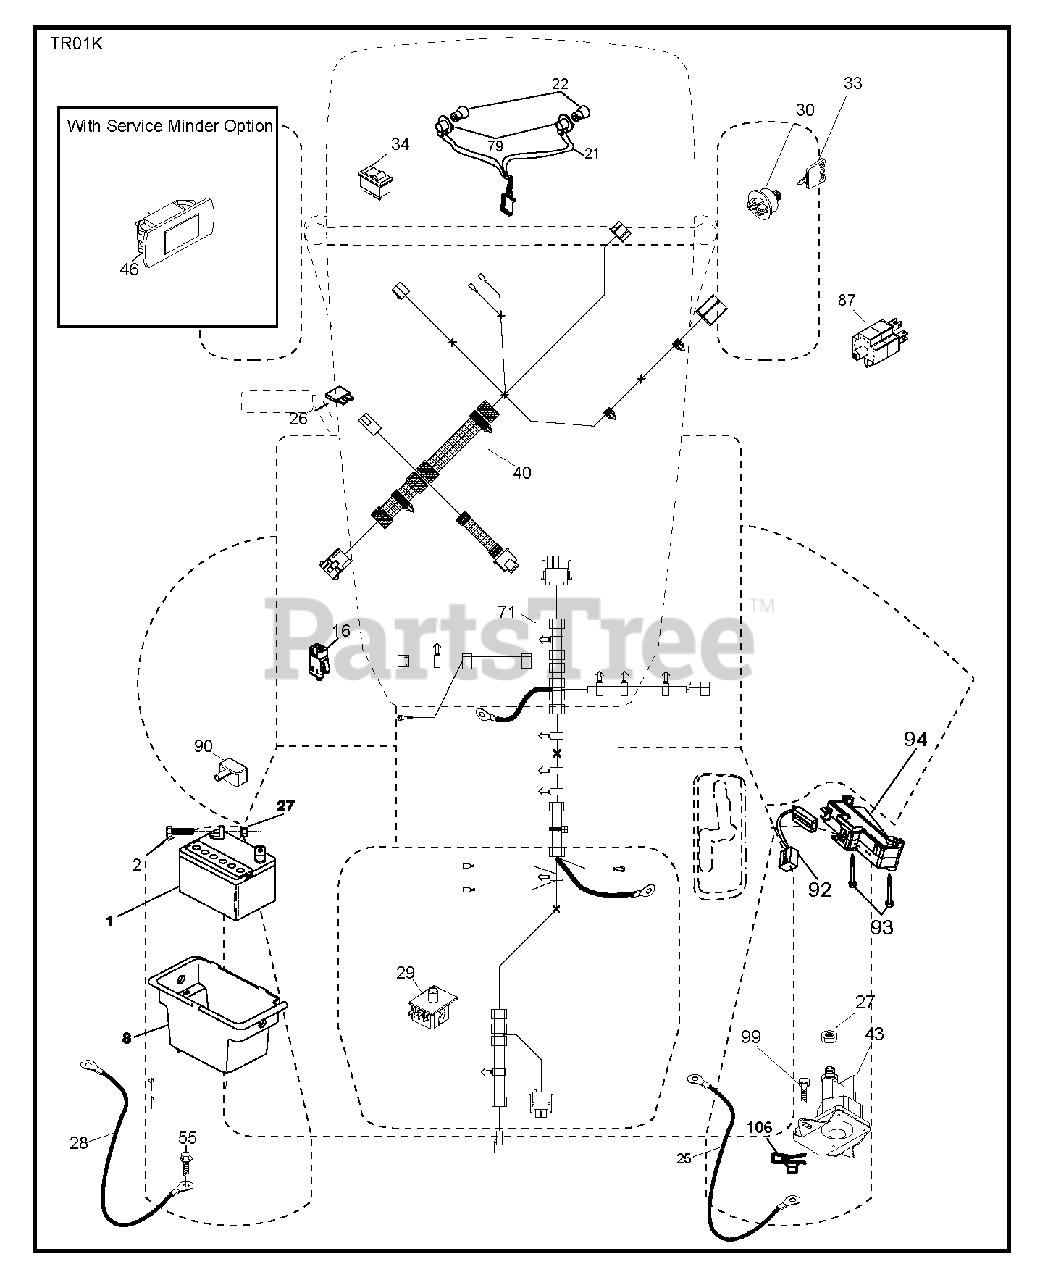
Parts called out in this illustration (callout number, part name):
1	REPL BY 532 12 38-99
2	BOLT.HEX.1/4.X.3/4.DICHROMATE
8	BOX.BATTERY.MNT.REAR.L
16	SWITCH INTERLOOK PUSH-IN
21	HARNESS.W/LIGHT SOCKET
22	LIGHTBULB
25	CABLE.BATT.RED.8GA.17
26	FUSE 20AMP
27	NUT
28	CABLE.GROUND.REAR.BATTERY.8G
29	SWITCH.SEAT.DP W/RAMPS
30	SWITCH.IGN.DELTA.W.LGH.ROS
33	KEY.CHAIN.BLISTER.PACK.GEN.INT
34	SWITCH LT
40	HARNESS.TEX.DASH.MAN.REAR BATT
43	SOLENOID.W/BRASS.PLUNGER
55	SCREW 5/16"
71	HARNESS.TEX.CHSSIS.REAR.BATT
79	BULB HOLDER ASM.
87	SWITCH.INTRLCK.CLUTCH.
90	COVER.TERMINAL.BATTERY
92	HARNESS.PIGTAIL.CONSLE
93	SCREW.PLASTITE
94	MODULE.REVERSE.ROS
99	SCREW HEXWSHR 1/4-20X3/4
106	1/4-20 U NUT
